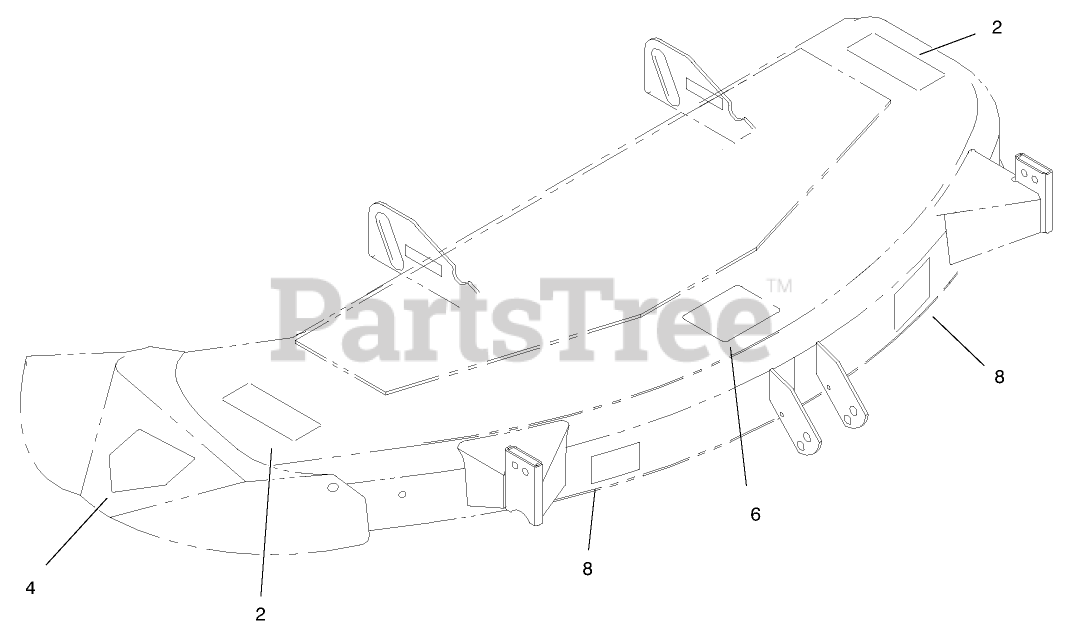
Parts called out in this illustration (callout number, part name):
2	DECAL-DANGER
4	DECAL-DANGER
6	DECAL-BELT INSTALLATION
8	DECAL-ADJUSTMENT, WHEEL
